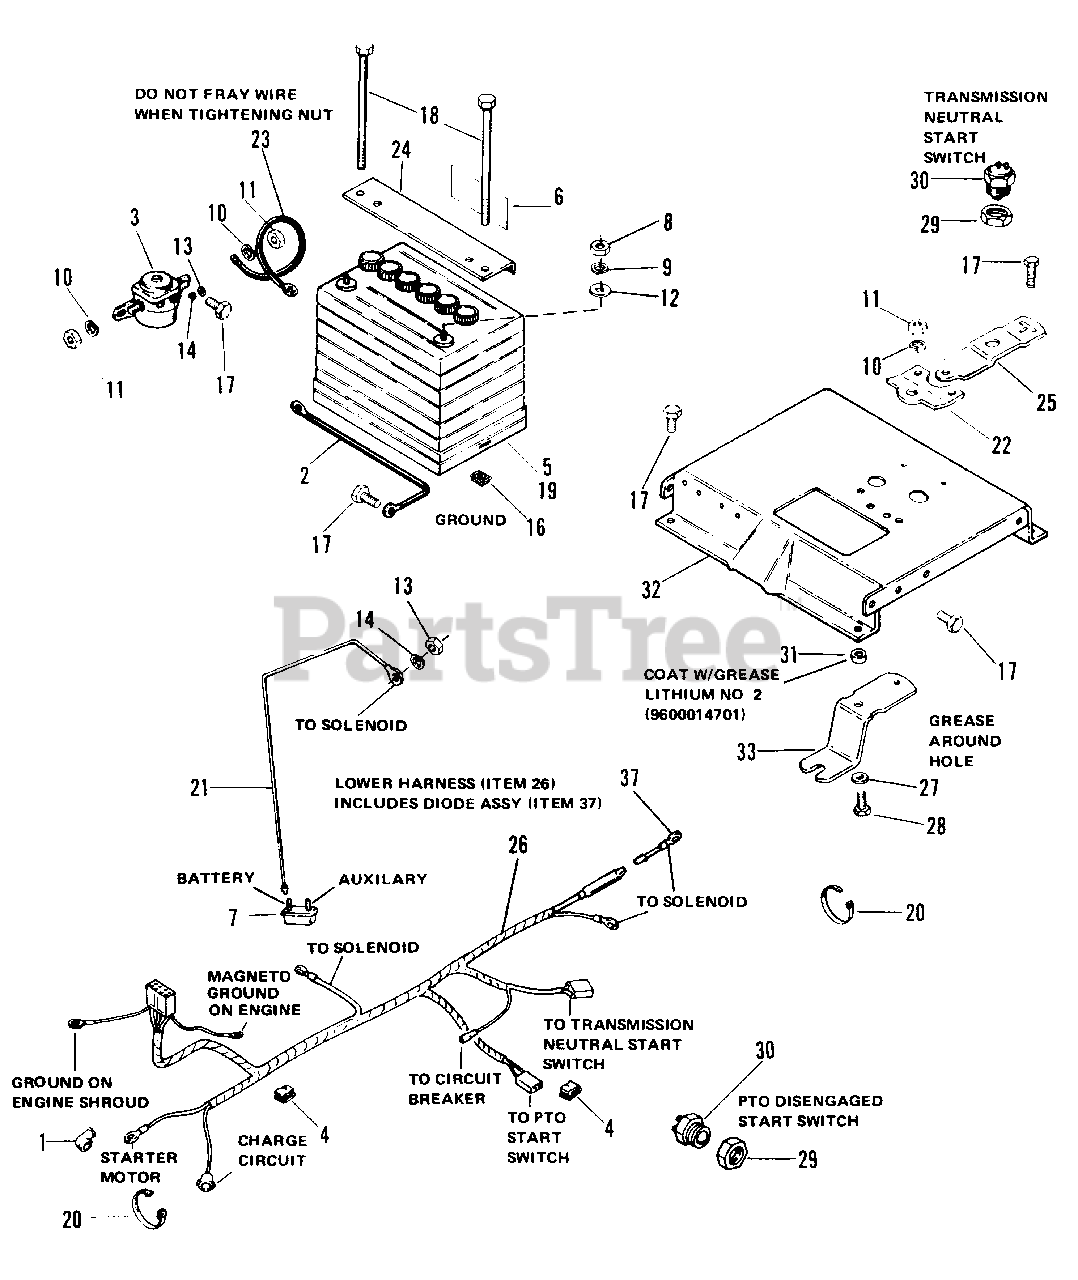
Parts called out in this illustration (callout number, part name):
1	COVER, Terminal
3	SOLENOID
4	CLIP, Speed
5	BATTERY (6008)
6	FILM, Battery
7	BREAKER, Circuit
8	NUT, Hex, 1/4-20
9	LOCKWASHER, Spring, 1/4
10	LOCKWASHER, Spring, 5/16
11	NUT, Hex, 5/16-18
12	WASHER, Plain, 1/4
13	NUT, Hex Mach., No. 10
14	LOCKWASHER, Ext. No. 10
16	NUT, Retainer, 1/4-20
17	SCREW, Hex Washer Hd, 1/4-20 x 3/8
18	CAPSCREW, Hex Hd., 1/4-20 x 7
19	BATTERY (6011)
22	PIVOT, Shift Lever
24	HOLD DOWN, Battery
25	BRACKET, Switch
26	HARNESS, Lower (03566)
28	CAPSCREW, Hex Hd., 5/16-18 x 1
29	LOCKNUT, 9/16-18
30	SWITCH, Interlock
32	SUPPORT, Frame
33	LEVER, Switch
37	DIODE ASSY (03566)
